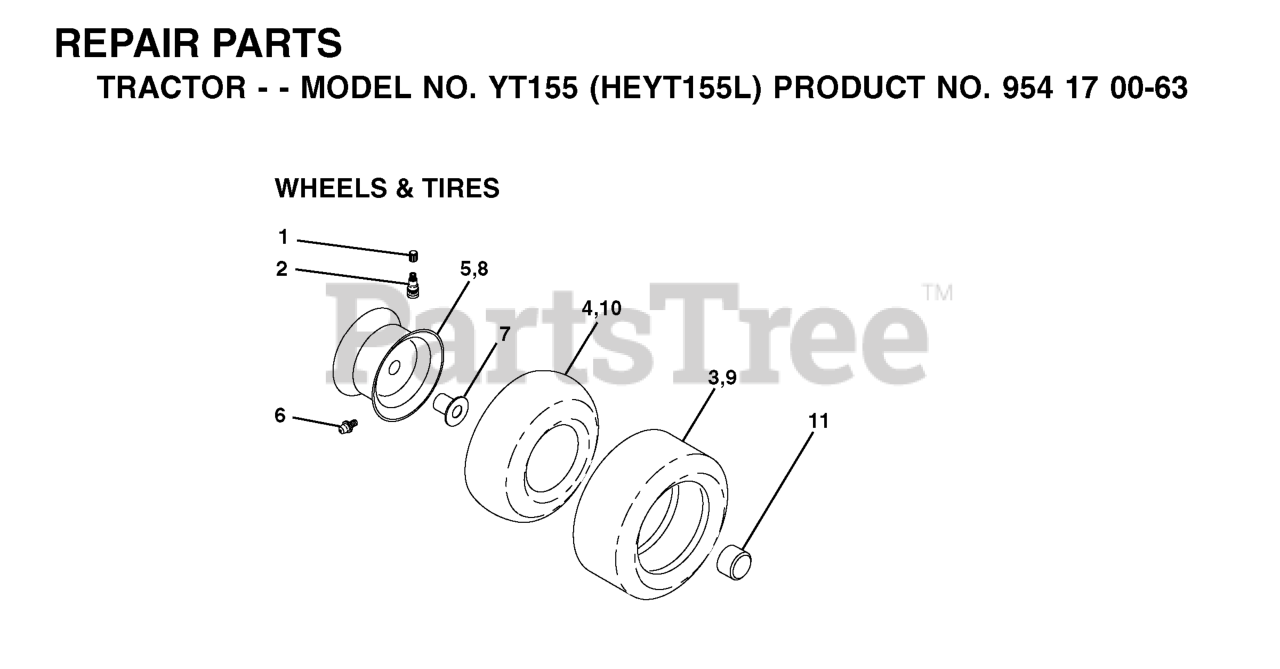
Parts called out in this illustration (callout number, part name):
2	VALVE STEM LT
3	TIRE HEAVY DUTY
4	TUBE.5.3/4.5/6
5	RIM ASM 6" FRONT SILVER
6	FITTING LT
7	BEARING T
8	RIM ASM 8" REAR SILVER
9	TIRE.TS.20X10-8
10	TUBE
11	CAP, AXLE BLK
